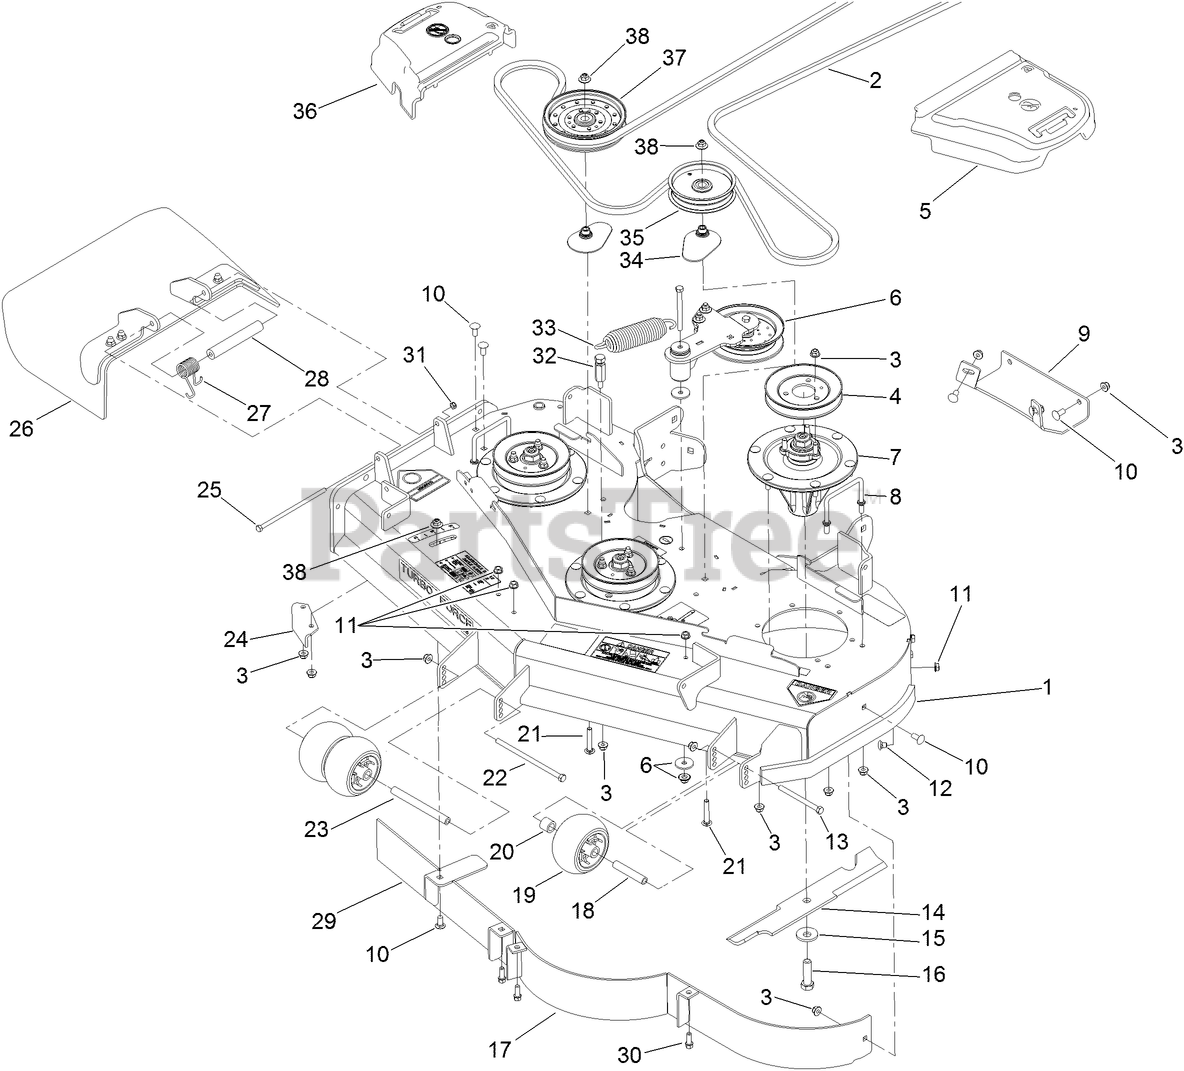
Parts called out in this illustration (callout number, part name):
1	DECK DECAL ASM
2	BELT-V
3	NUT-HF, NI
4	PULLEY
5	COVER-BELT, LH
6	IDLER ARM ASM
7	SPINDLE ASM
8	WIREFORM-COVER
9	PLATE-SKID
10	SCREW-CARR
11	NUT-HHF, WHIZ
12	SCREW-CARR
13	SCREW-HH
14	BLADE-16.5 INCH (HIGH FLOW)
15	Washer-Blade Bolt, Heavy
16	SCREW-BLADE
18	TUBE-SPANNER
19	ROLLER-SCALP, ANTI
20	TUBE-SPACER
21	BOLT-CARR, SHORT NECK
22	SCREW-HH
23	SPACER-WHEEL
24	BAFFLE-DISCHARGE
25	SCREW-HH
26	RUBBER DEFLECTOR ASM
27	SPRING-TORSION
28	SPACER
29	BAFFLE ASM
30	SCREW-HWH
31	NUT-LOCK, NI
32	ANCHOR-SPRING, TALL
33	EXTENSION-SPRING
34	SPACER-PULLEY
35	PULLEY-IDLER
36	COVER-BELT, RH
37	PULLEY-IDLER, FLAT
38	NUT-FLANGE, NI
